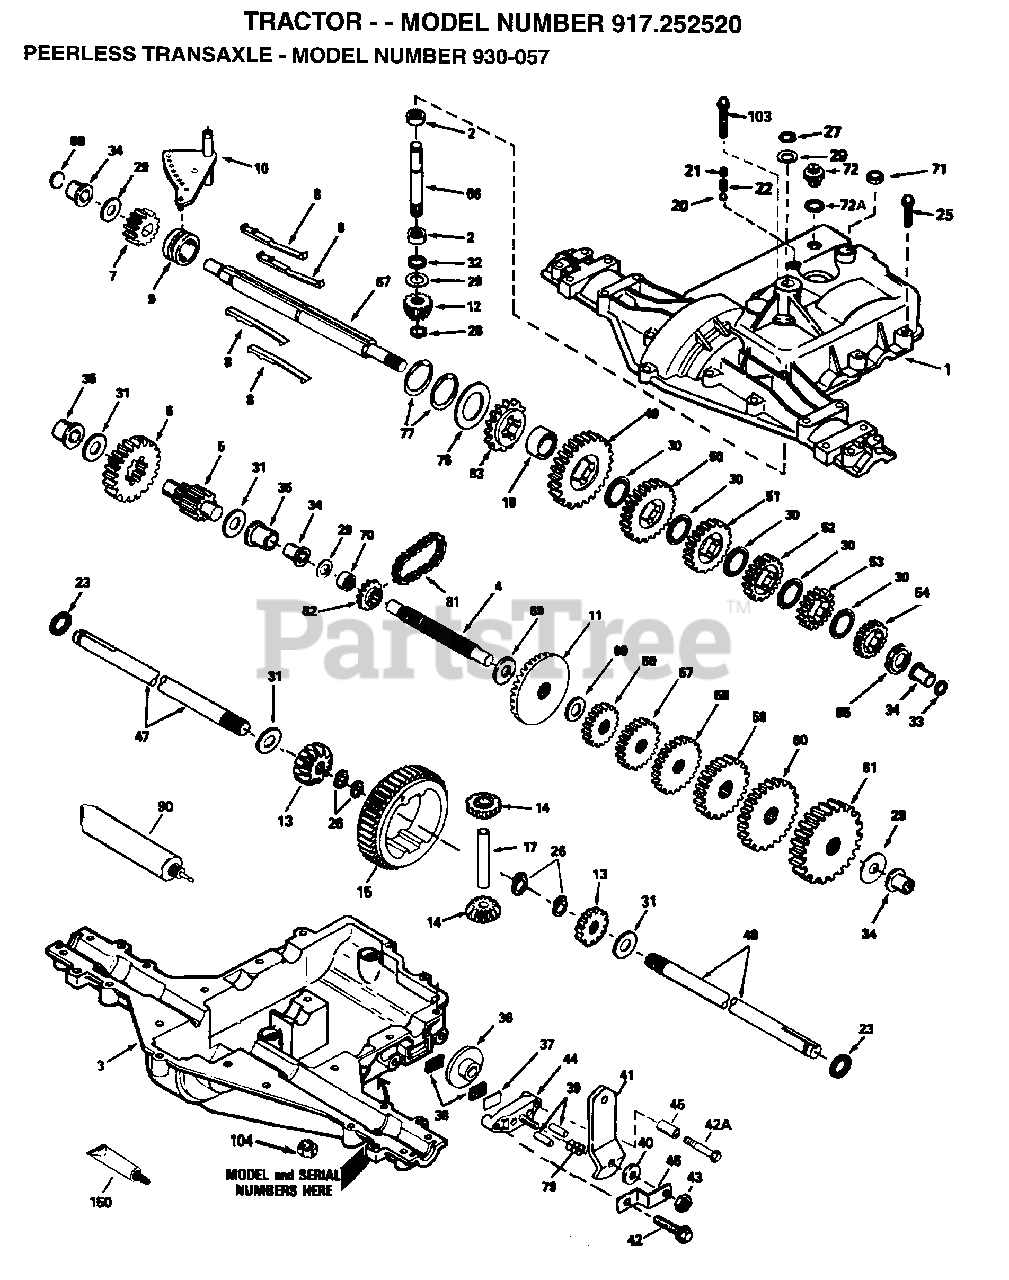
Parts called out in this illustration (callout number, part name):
1	TRANSAXLE COVER
2	BEARING, NEEDLE
3	TRANSAXLE CASE
4	SHAFT, COUNTER
5	OUTPUT SHAFT AND PINION
6	GEAR, OUTPUT
7	GEAR, SPUR, 15 TEETH
9	COLLAR, SHIFTER
10	ROD & FORK ASSY, SHIFT
11	GEAR, BEVEL, 42 TEETH
12	BEVEL PINION, INPUT
13	GEAR, BEVEL
14	GEAR, BEVEL, PINION
18	SPACER, NEUTRAL
20	BALL STEEL, 5/16" DIA.
21	SCREW, 3/8-16 X 3/8"
25	SCREW, 1/4-20 X 1-1/4
26	RING RETAINER
27	RING, RETAINER
28	RETAINING RING
29	WASHER THRUST
30	WASHER THRUST
33	SEAL, SQUARE CUT
34	BUSHING, FLANGED
35	BUSHING, FLANGED
36	DISK, BRAKE
37	PLATE BRAKE PAD
41	BRAKE LEVER
42	SCREW, 1/4-20 X 1-1/4
42A	SCREW, 1/4-20 X 2-1/4
43	LOCKNUT 5/16-24
44	HOLDER BRAKE PAD
46	BRKT BRAKE LEVER
49	GEAR, SPUR, 37 TEETH
50	GEAR, SPUR, 35 TEETH
51	GEAR, SPUR, 30 TEETH
52	GEAR, SPUR, 25 TEETH
53	GEAR, SPUR, 22 TEETH
54	GEAR, SPUR, 19T
56	GEAR, SPUR, 12 TEETH
57	GEAR, SPUR, 15 TEETH
58	GEAR, SPUR, 20 TEETH
59	GEAR, SPUR, 25 TEETH
60	GEAR, SPUR, 28 TEETH
61	GEAR, SPUR, 31 TEETH
65	WASHER, THRUST
66	SHAFT, INPUT
67	SHAFT, BRAKE, 4 KEYED
69	WASHER THRUST
71	SEAL SQUARE CUT
72	THREADED PLUG 9/16-18
76	WASHER, THRUST
77	INVERTED RETAINING RING
81	CHAIN, ROLLER
82	SPROCKET 9T
83	SPROCKET 18T (REV)
90	GREASE BENTONITE, 32 OZ.
150	GASKET ELIMINATOR
